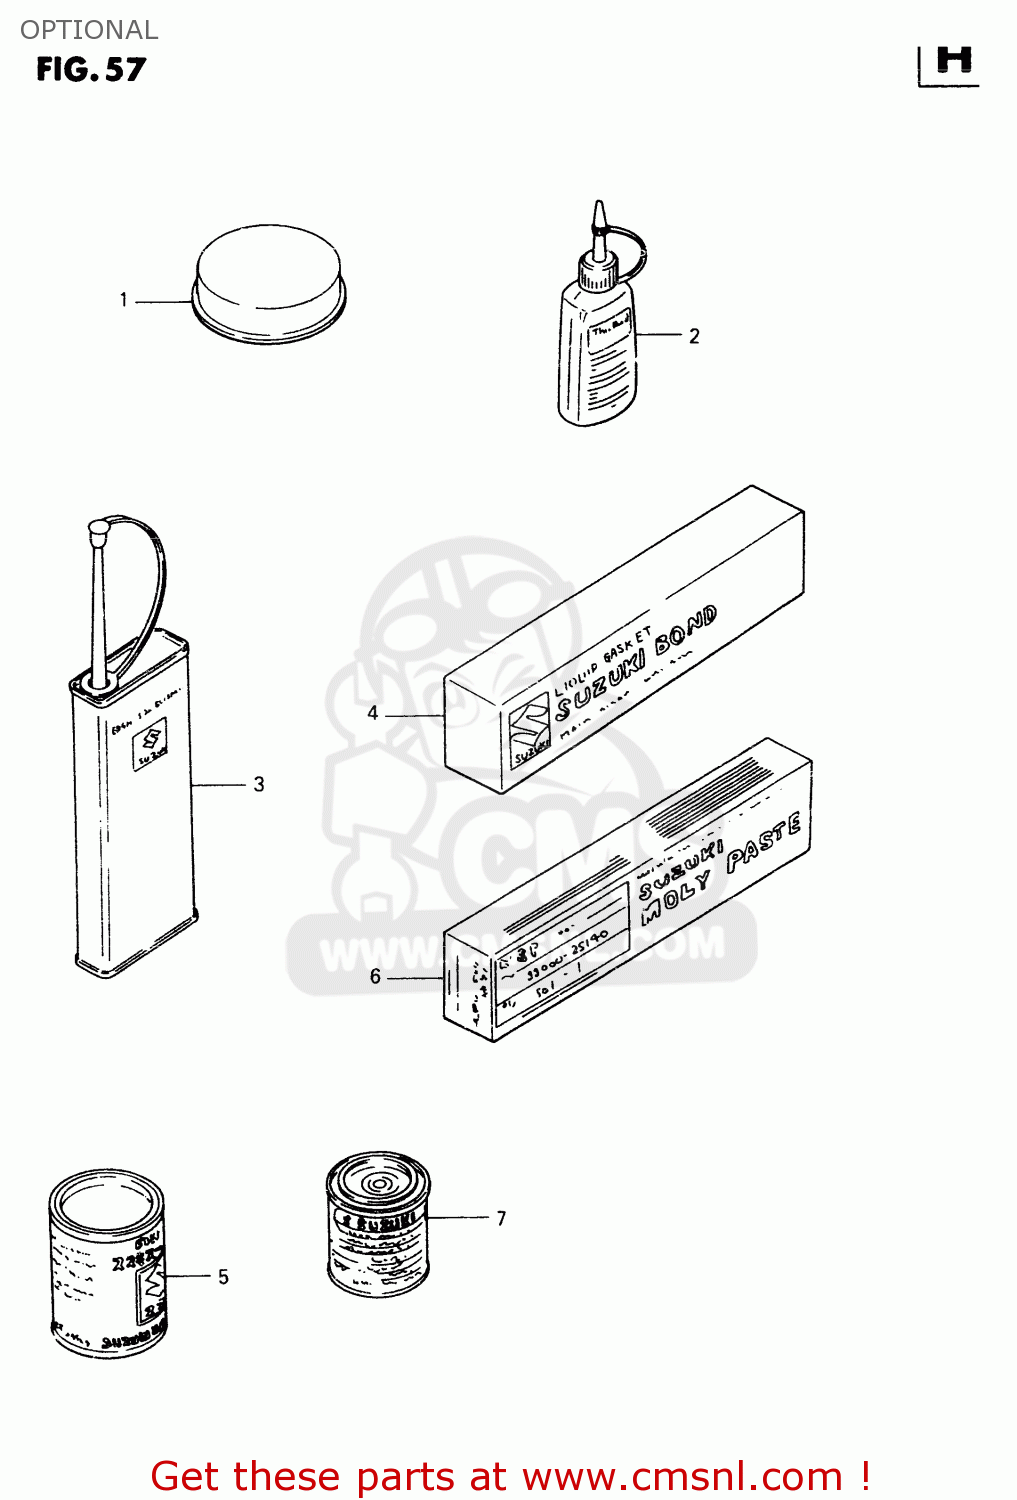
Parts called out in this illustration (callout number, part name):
1	GREASE,PBC FOR BRK PAD 20G
2	THREAD LOCK NO.1342
3	THREAD LOCK NO.1401 CLEAR 200G
4	LIQUID GSKT NO.1215 250G
5	GREASE(C)EP2 LITHIUM 150G
6	SUZUKI MOLY PASTE
7	PAINT,BLACK
